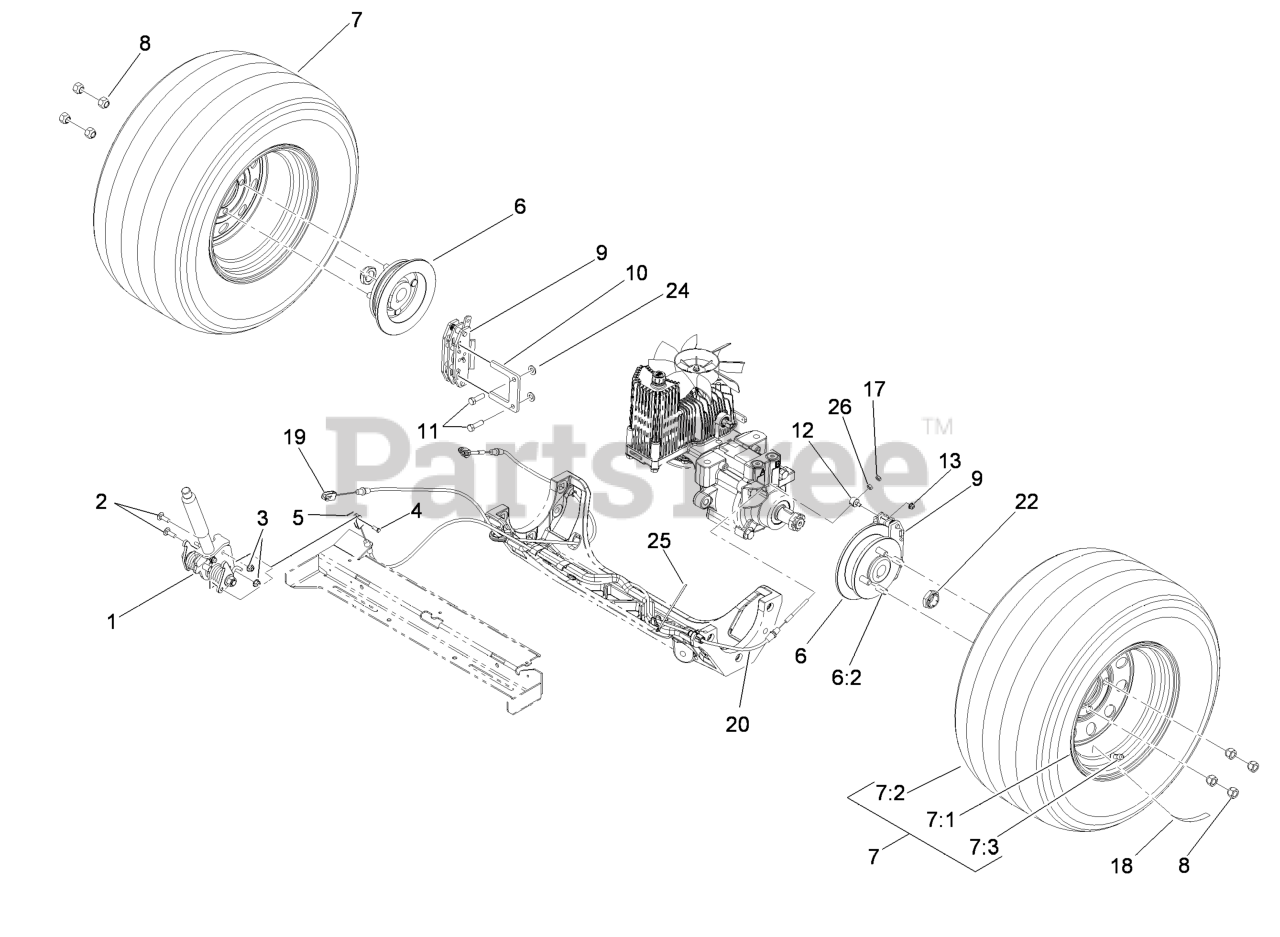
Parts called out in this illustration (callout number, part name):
1	BRAKE HANDLE ASM
2	BOLT-CARR
3	NUT-HF, NI
4	PIN-CLEVIS
5	PIN-COTTER
6	WHEEL HUB ASM
6:2	STUD-WHEEL
7	WHEEL AND TIRE ASM
7:1	RIM ASM
7:2	TIRE
7:3	Stem-Valve
8	NUT-LUG
9	CALIPER-BRAKE
10	PLATE-MOUNT, BRAKE
11	SCREW-LOCK, PATCH
17	NUT-LOCK, NI
22	LOCKNUT
24	WASHER-FLAT
25	TIE-CABLE
26	NUT-HEX
